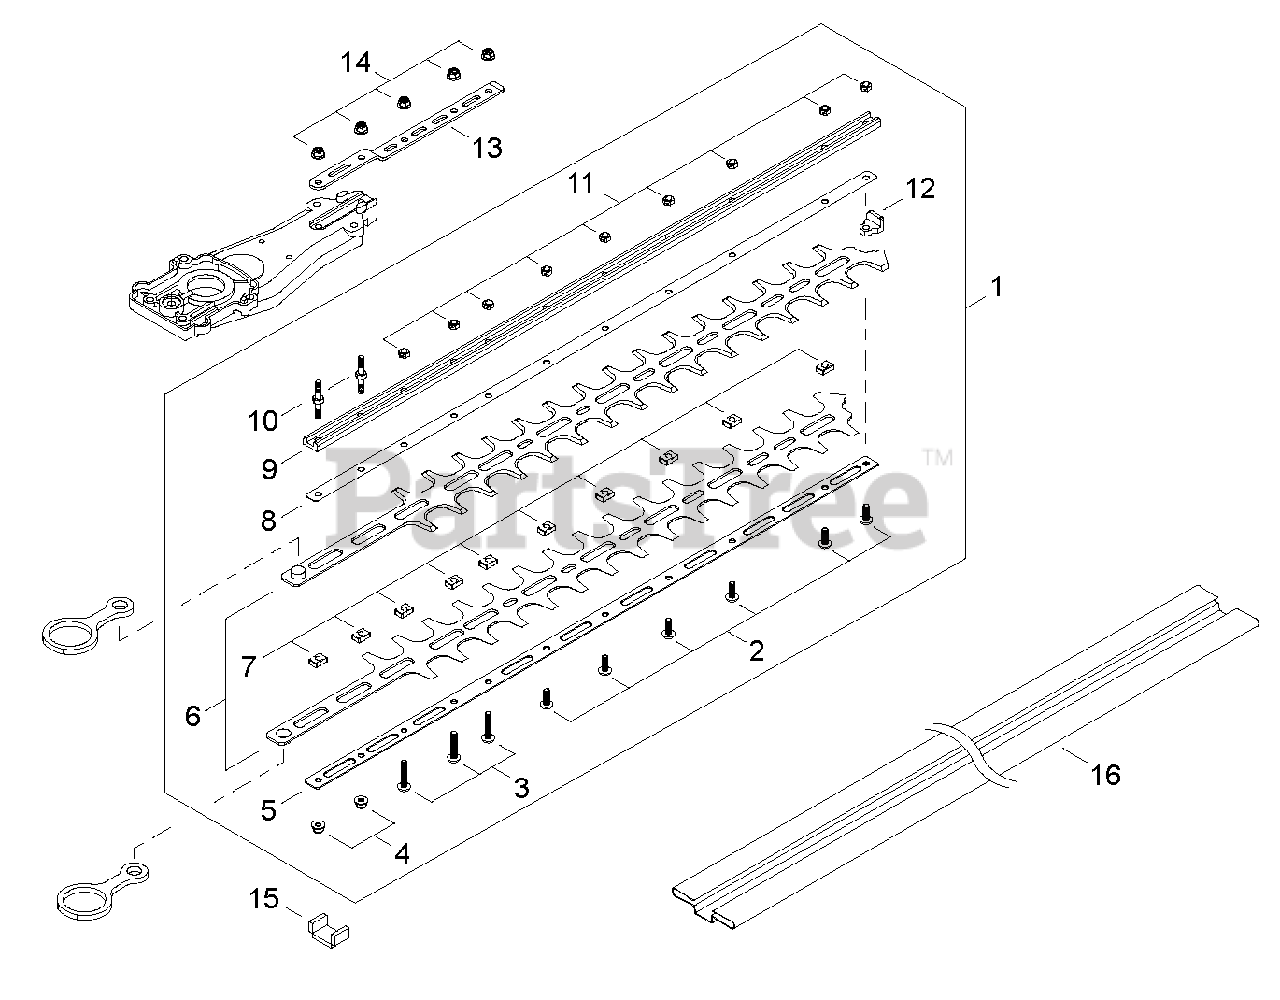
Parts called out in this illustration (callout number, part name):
1	BLADE KIT - 24" (60cm)
2	SCREW - 5X14
3	SCREW - 5X25
4	NUT - 5
5	PLATE - LOWER
6	BLADE - 24" (60cm)
7	SPACER
8	PLATE - UPPER
9	SUPPORT, BLADE - 24" (60cm)
10	STUD - 5
11	LOCKNUT - 5
12	BLOCK
13	BRACKET, CUTTER
14	NUT - 5
15	SEAL, FELT
16	COVER, BLADE - 24" (60cm)
